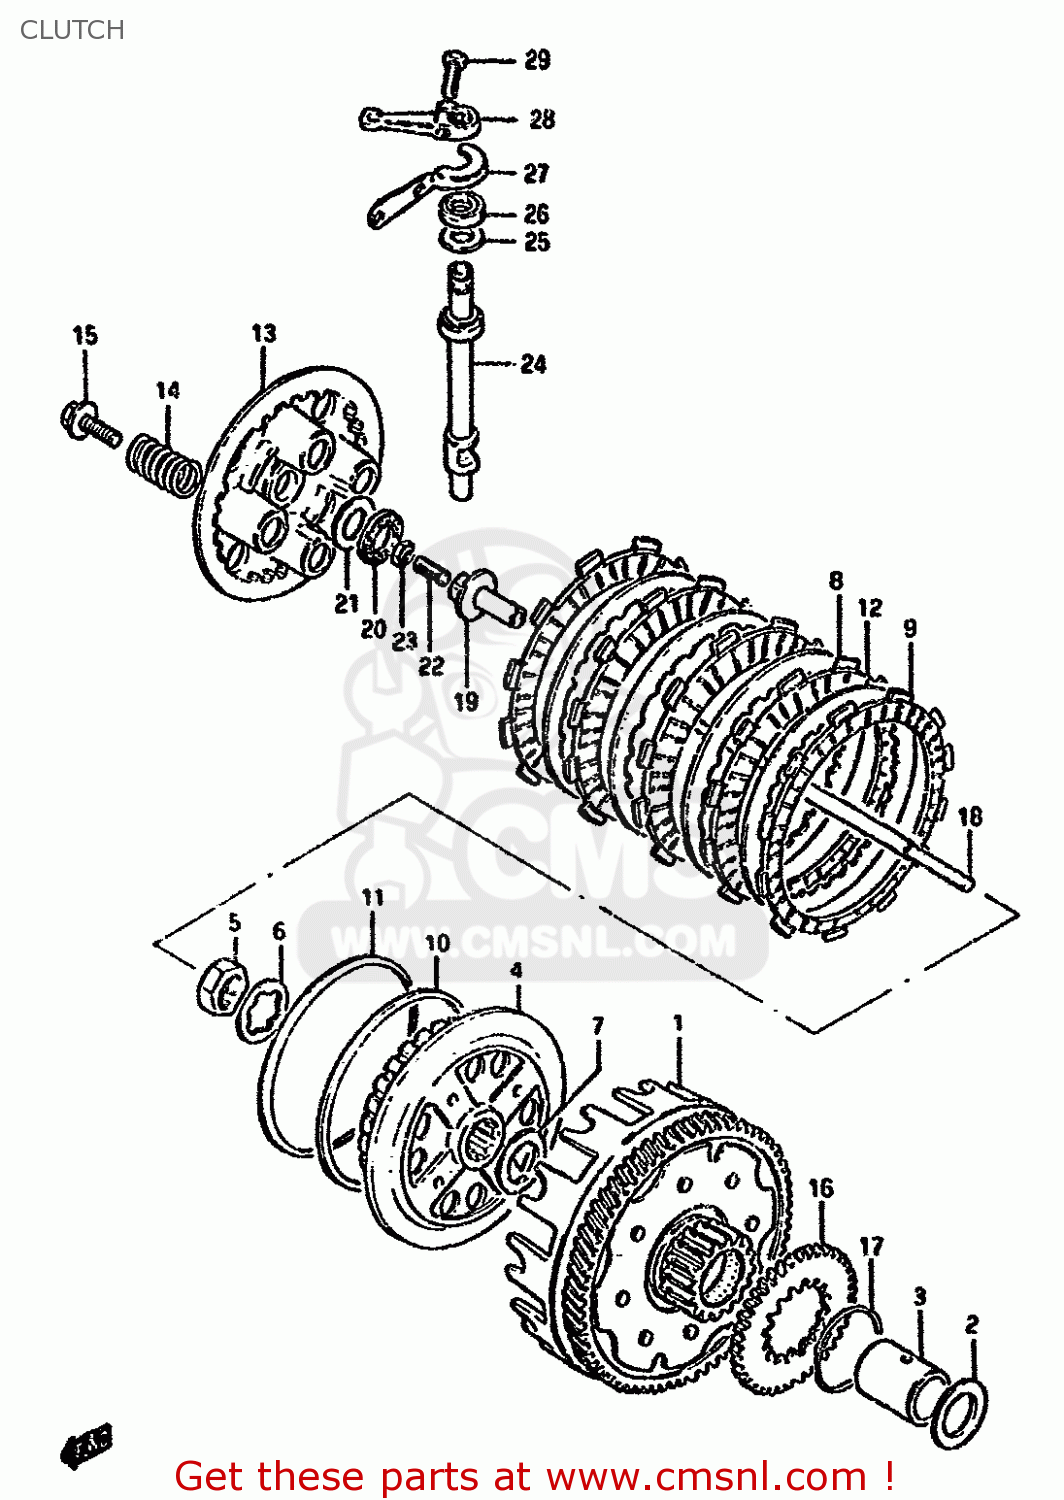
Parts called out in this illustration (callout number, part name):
1	GEAR ASSY,PRI DRIVEN
2	WASHER
3	SPACER(22X28X37.5)
4	HUB,CLUTCH SLEEVE
5	NUT
6	WASHER,LOCK
7	WASHER
8	PLATE,CLUTCH DRIVE (NAS)
9	PLATE,CLUTCH DRIVE(T:3.5) (NAS)
10	SEAT,WAVE WASHER(T:1.4)
11	WASHER
12	PLATE,CLUTCH DRIVEN
13	DISC,CLUTCH PRESSURE
14	SPRING
15	BOLT
16	GEAR,OIL PUMP DRIVE
17	CIRCLIP
18	ROD,CLUTCH PUSH
19	PIECE,CLUTCH PUSH
20	BEARING(15X28X2)
21	WASHER(15.5X28X1)
22	SCREW(6X25)
23	NUT
24	CAMSHAFT,CLUTCH RELEASE
25	WASHER (14.2X22X1)
26	OIL SEAL
27	PLATE,CLUTCH RRS CAMSHAFT SEAL
28	ARM,CLUTCH RELEASE
29	BOLT
